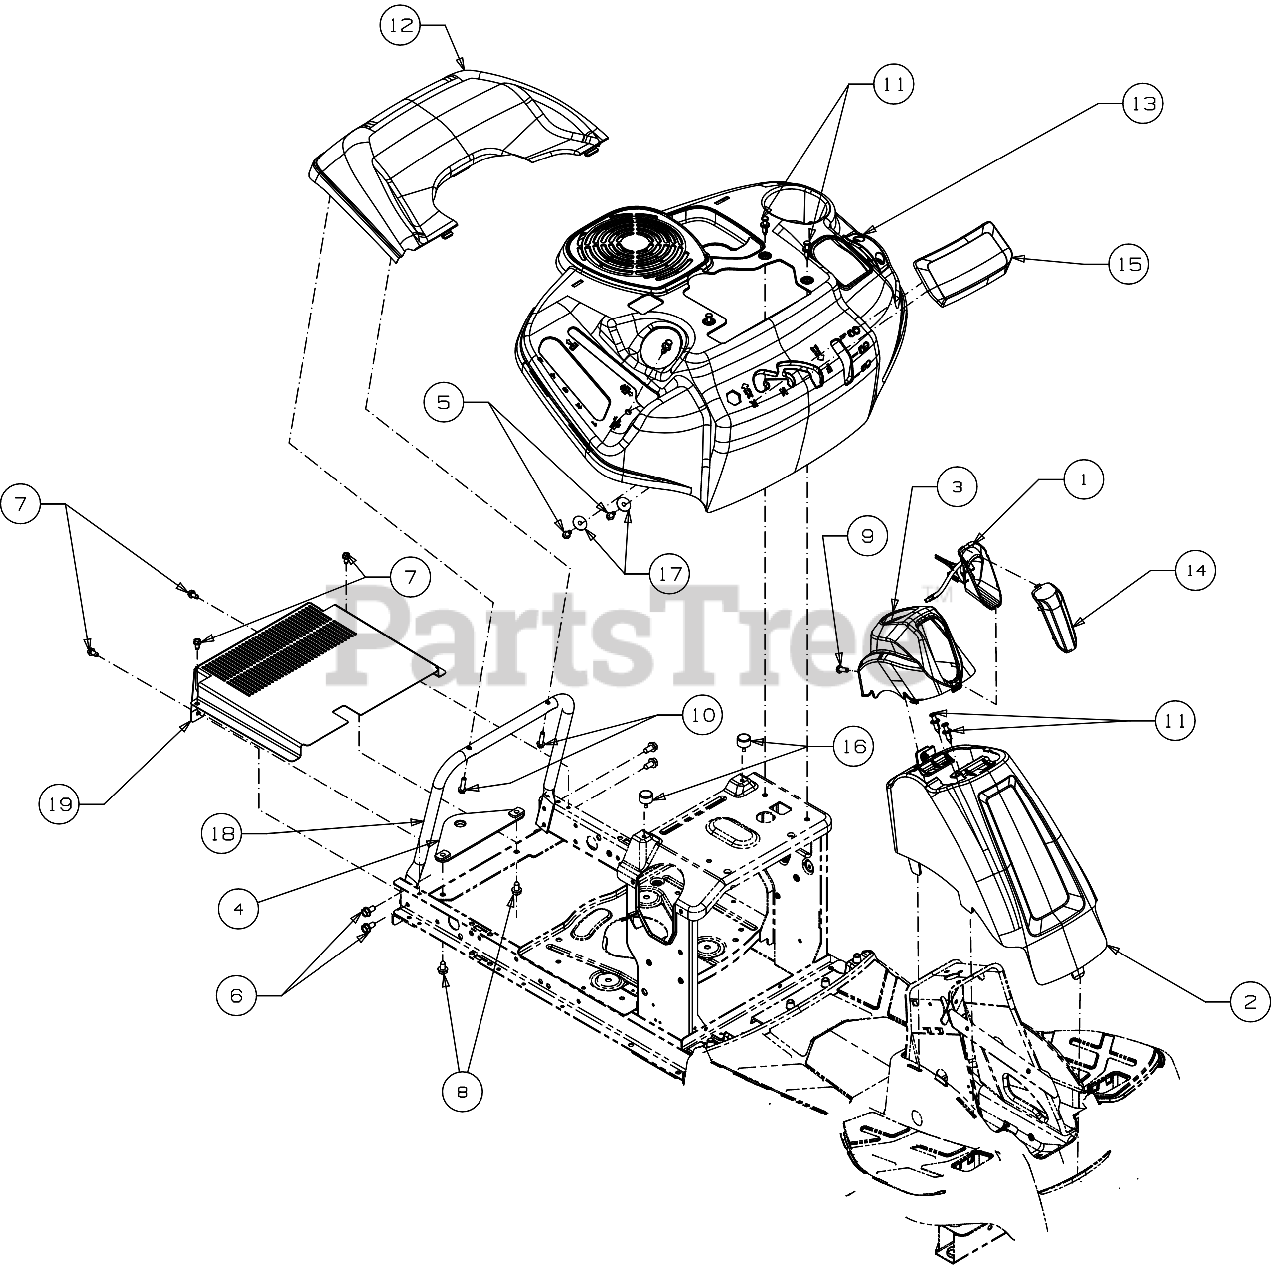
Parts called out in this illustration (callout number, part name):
1	LED HEADLIGHT HARNESS ASSEMBLY
2	COLUMN COVER ASSEMBLY (MTD RED)
3	STEERING COLUMN CAP (MTD RED)
5	HEX SCREW 1/4-15 x .50
6	SCREW 5/16-18 x .750
7	SCREW 1/4-20 X.500
8	SCREW 5/16-18 x .625
9	SCREW 1/4-20X.75
10	SCREW 1/4-15 x 1.00
11	PLASTIC RIVET
13	FENDER (MTD RED)
14	LED HEADLIGHT LENS
15	FENDER COVER
16	BUMPER .62 DIA x .50
17	FLAT WASHER
19	HYDRO COVER HEAT SHIELD
